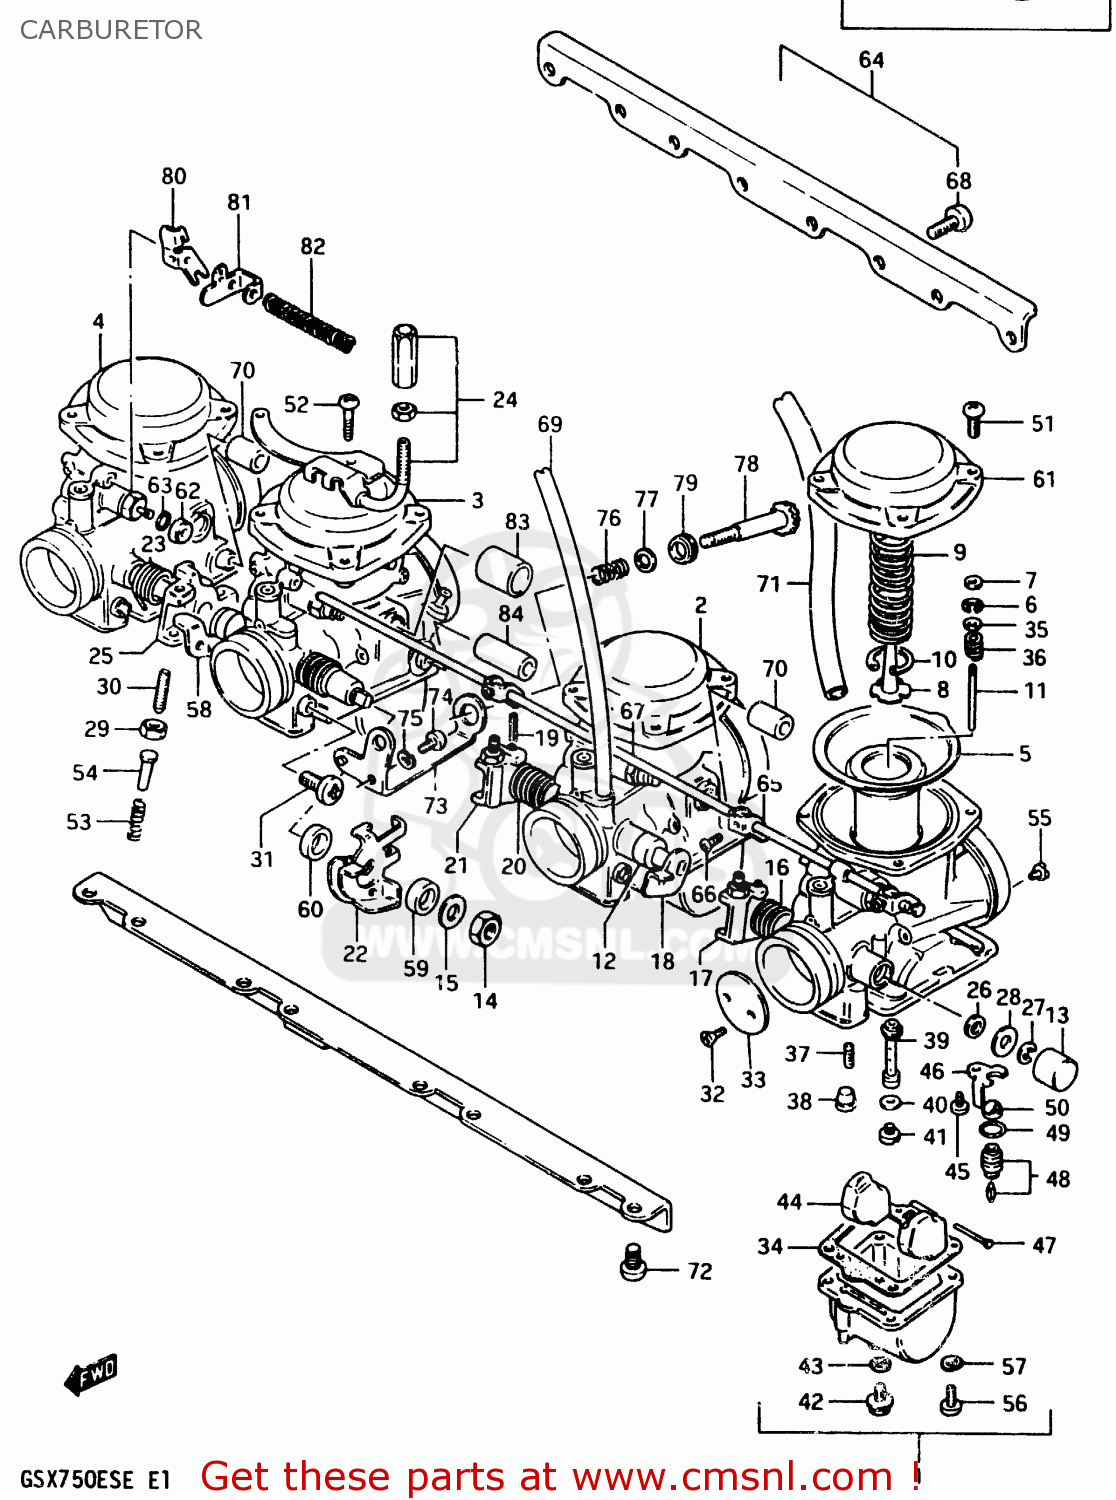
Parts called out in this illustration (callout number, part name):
1	CARBURETOR, LH
2	CARBURETOR, ML
3	CARBURETOR, MR
4	CARBURETOR, RH
5	DIAPHRAGM
6	CLIP,NEEDLE
7	RING
8	HOLDER,GUIDE
9	SPRING,DIAPHRAGM
10	E RING
11	NEEDLE, JET (5D10-3)
12	GASKET
13	CAP
14	NUT 8MM
15	WASHER
16	SPRING,THROTTLE SHAFT
17	SHAFT,THROTTLE
18	SHAFT,THROTTLE
19	PIN,THROTTLE SHAFT
20	SPRING,THROTTLE SHAFT
21	LEVER,THROTTLE SHAFT
22	LEVER ASSEMBLY,THROTTLE
23	SPRING,THROTTLE SHAFT
24	BRACKET,THROTTLE CABLE
25	SHAFT,THROTTLE
26	SEAL
27	E RING
28	GASKET,THROTTLE SHAFT (NAS)
29	NUT
30	SCREW
31	SCREW
32	SCREW
33	VALVE,THROTTLE (BUTTERFLY)
34	GASKET,FLOAT CHAMBER (NAS)
35	WASHER
36	SPRING
37	JET(40)
38	PLUG,NEEDLE JET
39	JET, NEEDLE (Y-7)
40	WASHER,NEEDLE NOZZLE
41	JET
42	PLUG,DRAIN
43	GASKET (NAS)
44	FLOAT
45	SCREW 4X6
46	PLATE,NEEDLE VALVE FITING
47	PIN,FLOAT
48	VALVE ASSEMBLY,NEEDLE
49	O-RING,NEEDLE VALVE
50	FILTER
51	SCREW
52	SCREW
53	SPRING,THROTTLE SCREW
54	PIN,THROTTLE LEVER
55	JET,AIR
56	SCREW
57	LOCK WASHER
58	SHAFT,THROTTLE
59	RING
60	RING
61	COVER
62	CAP,STARTER VALVE
63	O RING
64	FLANGE ASSEMBLY,CARBURETOR
65	LEVER
66	SCREW,THROTTLE ADJUST
67	SHAFT,STARTER
68	SCREW
69	HOSE 4.5X8X390
70	NIPPLE,CARBURETOR
71	HOSE
72	SCREW 6X12
73	BRACKET,THROTTLE ADJUST
74	SCREW
75	LOCK WASHER
76	SPRING
77	WASHER
78	ADJUSTER
79	BUSH
80	LEVER,CHOKE CABLE
81	PLATE,CHOKE CABLE
82	SPRING,CHOKE CABLE
83	HOSE
84	NIPPLE,CARBURETOR
